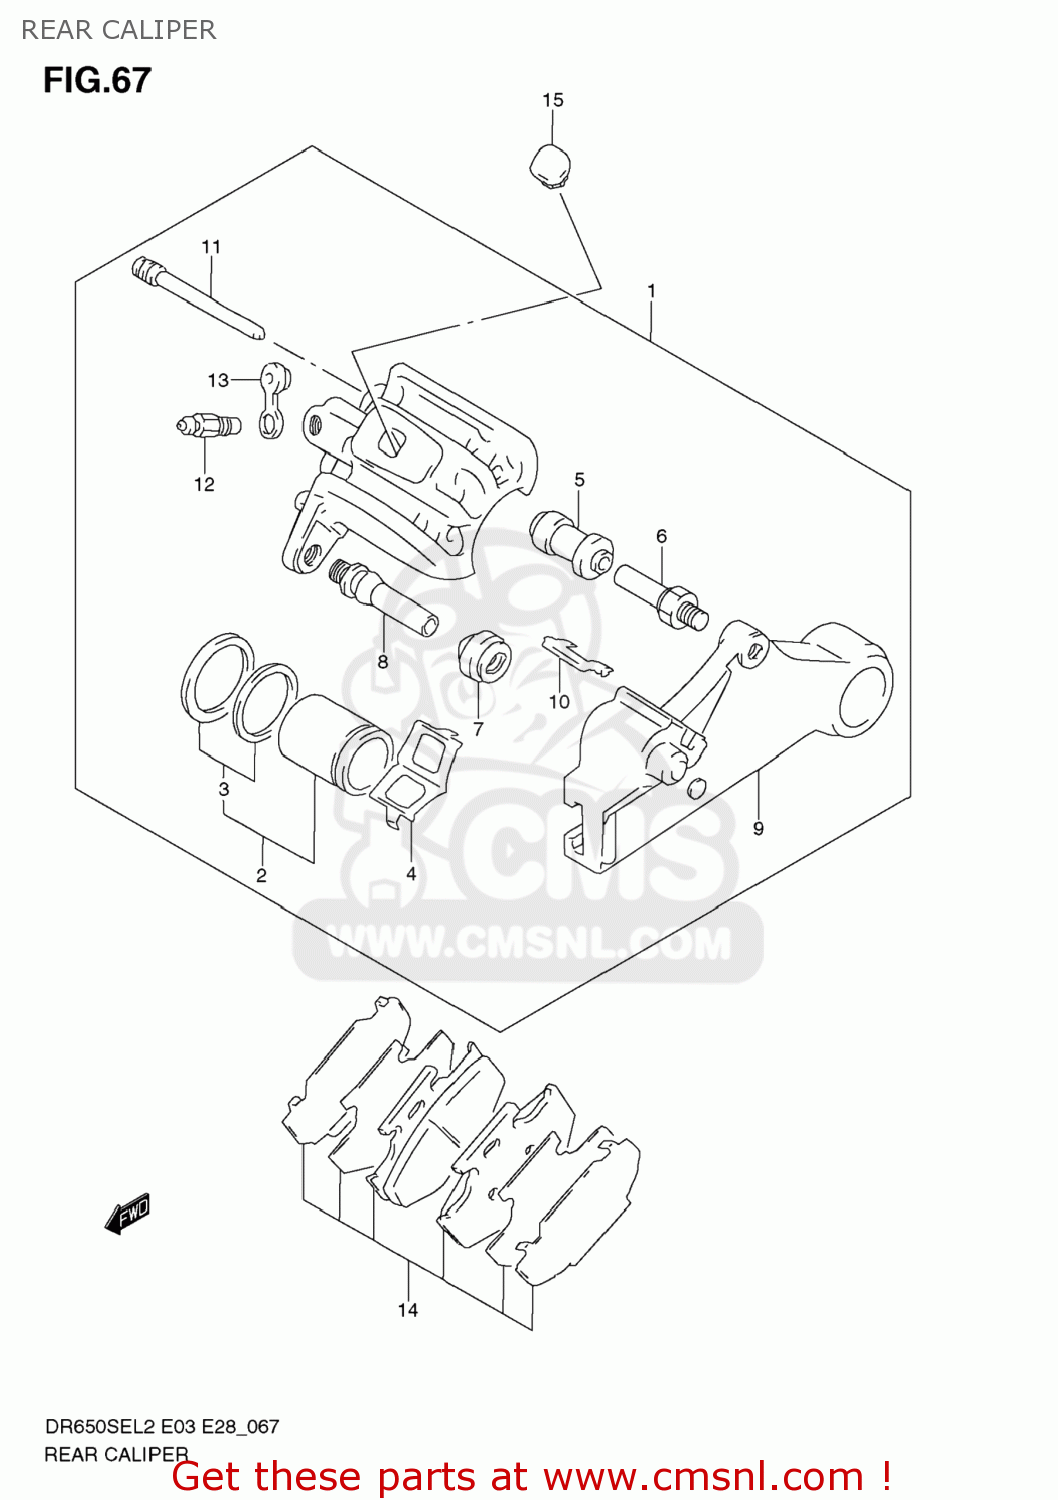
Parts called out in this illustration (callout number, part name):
1	CALIPER ASSY,RR
2	PISTON SET
3	SEAL SET,PISTON
4	SPRING,PAD
5	BOOT
6	BOLT
7	BOOT
8	PIN
9	BRACKET
10	RETAINER,BRACKET
11	PIN,HANGER
12	BLEEDER
13	CAP,BLEEDER
14	PAD & SHIM SET (NAS)
15	COVER,RR CALIPER BODY
